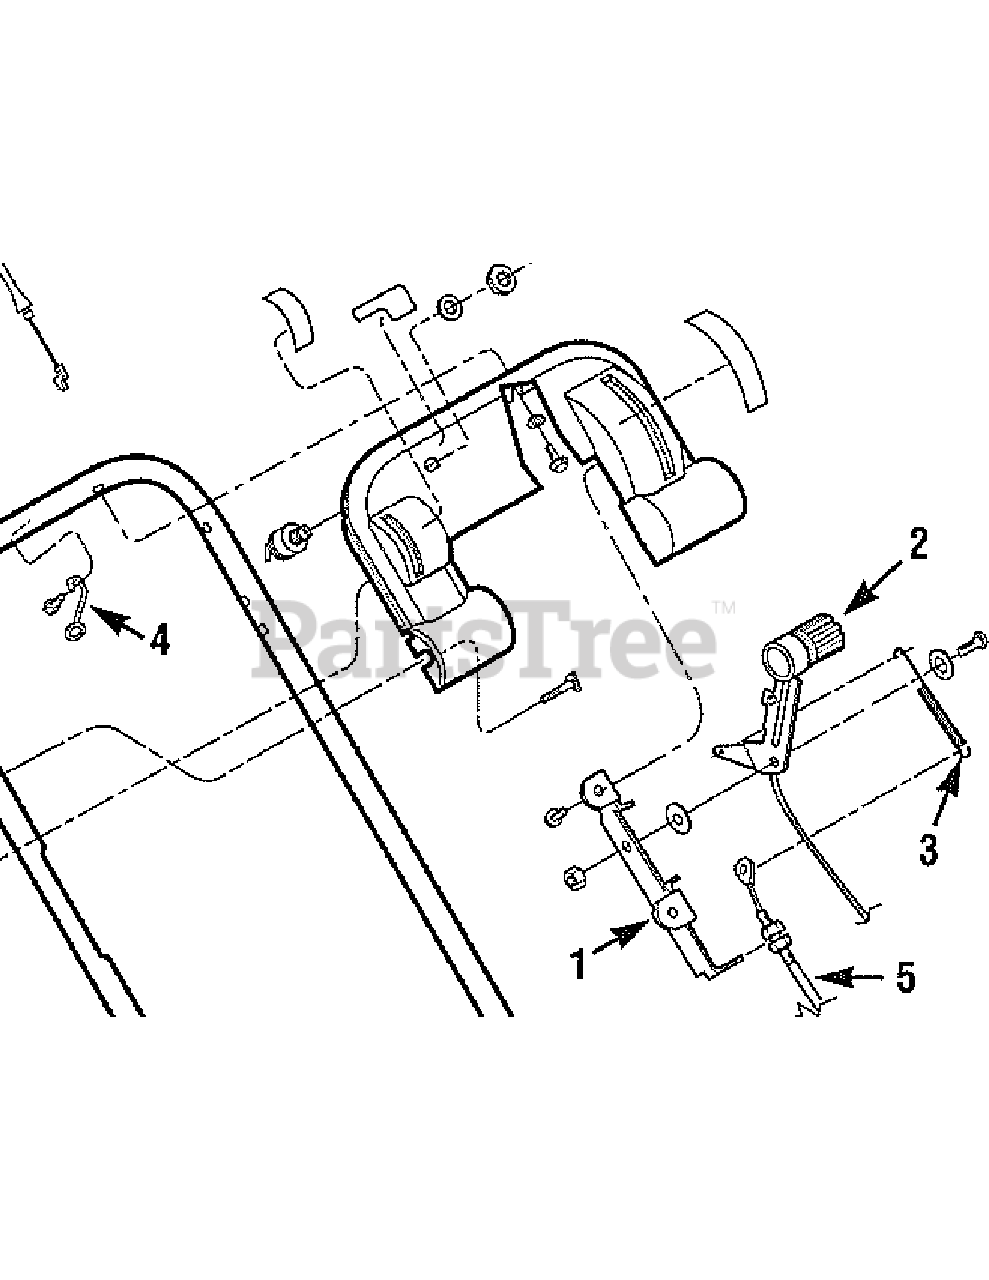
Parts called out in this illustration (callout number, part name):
1	BRACKET, CONTROL DRIVE {34022,34023}
2	ARM ASSM, DRIVE CONTROL, WITH SPEED CONTROL CABLE {34022,34023}
3	SPRING-EXTENSION {34022,34023}
4	GUIDE-ROPE {34022,34023}
5	CABLE-DRIVE CONTROL CLUTCH {34022,34023}
